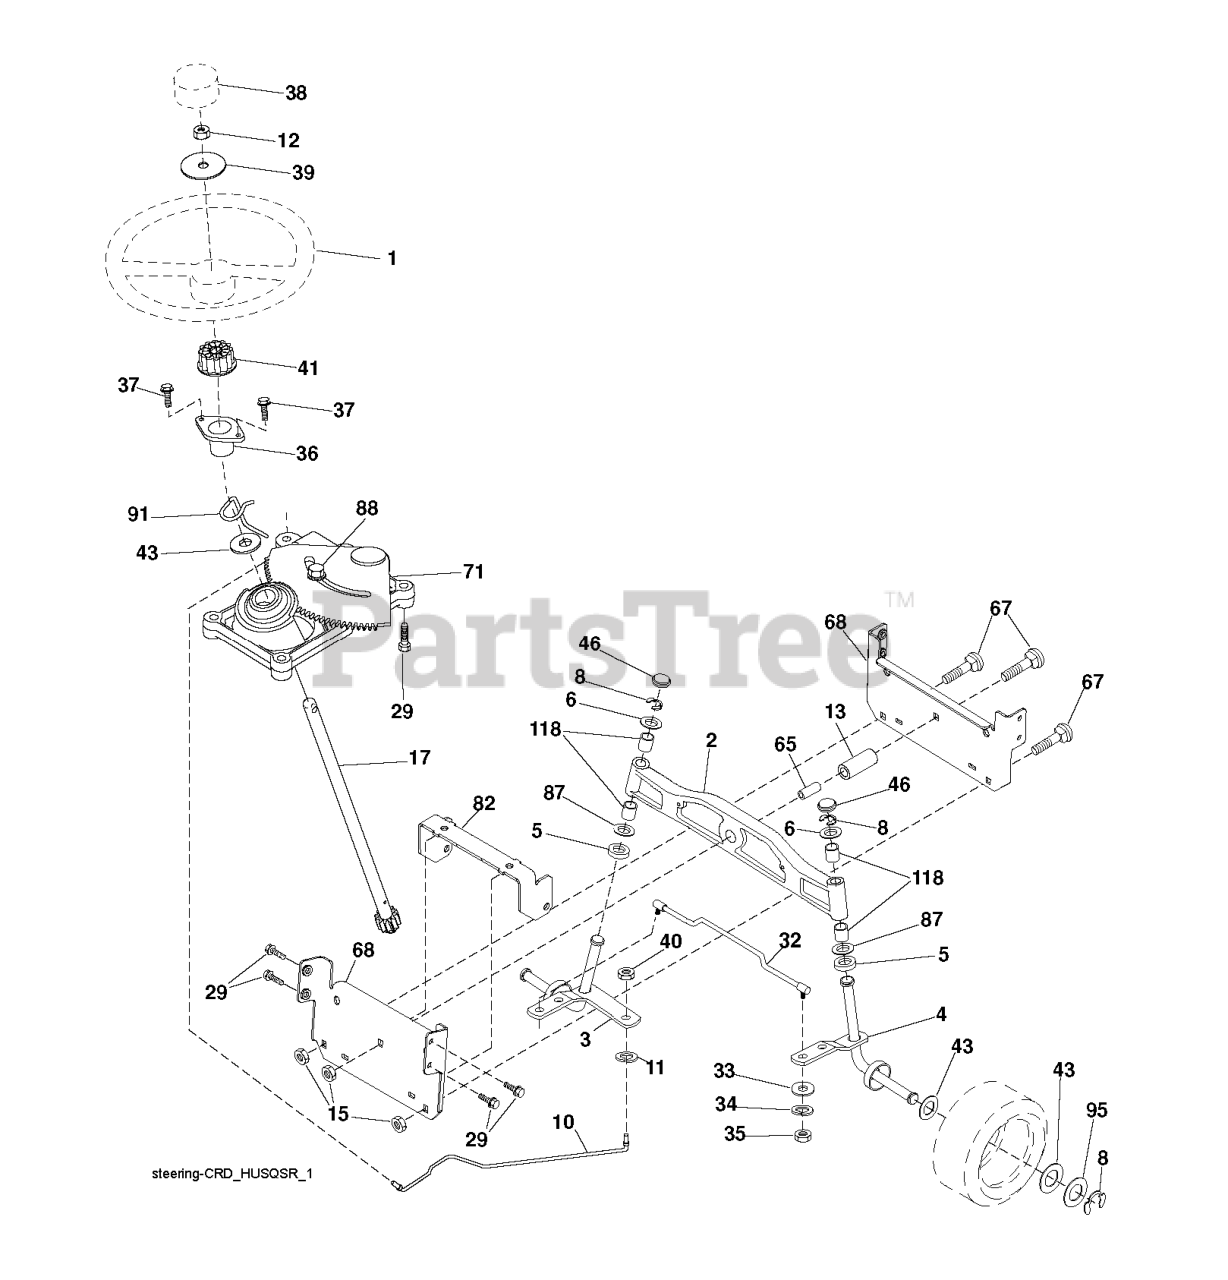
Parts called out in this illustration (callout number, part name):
1	WHEEL.STEER.HUSQ.SR.498.OVMLD
2	AXLE.ASM.LT.CAST.LGHTWGHT
3	SPINDLE.ASM.LH.15"TIRES
4	SPINDLE.ASM.RH.15"TIRES
5	THRUST WASHER
10	DRAGLINK.15".TIRES.2001
11	WASHER, LOCK 3/8
12	NUT.HEX.1/2-20
13	TUBE, PIVOT AXLE
15	NUT LOCK FLG 3/8-16 UNC
17	SHAFT ASM STRG
29	SCREW, 3/8-16X3/4
33	WASHER M
34	WASHER.LOCK.HVY.HLCL.SPR.5/16
35	NUT, CROWNLOCK
36	BUSHING, STRG. BLK
37	SCREW.TT.#10-32X.5.3/8.FLANGE
38	INSERT.CAP.WHL.STRG.HUSQ.PREM
39	WASHER 9/16"ID, 2 3/8"OD
40	NUT CROWNLOCK 3/8-24
41	ADAPTER, WHEEL STNG..
46	CAP.SPINDLE.BLACK
65	SPACER.BRACE.AXLE
67	BOLT CARRIAGE
68	BRACE.AXLE.15"TIRES
71	STEERING ASM
82	BRACKET.SUSP.CHASSIS.FRONT.15
87	WASHER, FLAT .781 X 1 1/2"
88	BOLT, SHOULDER 7/16-20
91	CLIP.STEERING
95	WASHER.HARDENED
118	BUSHING, AXLE CAST
